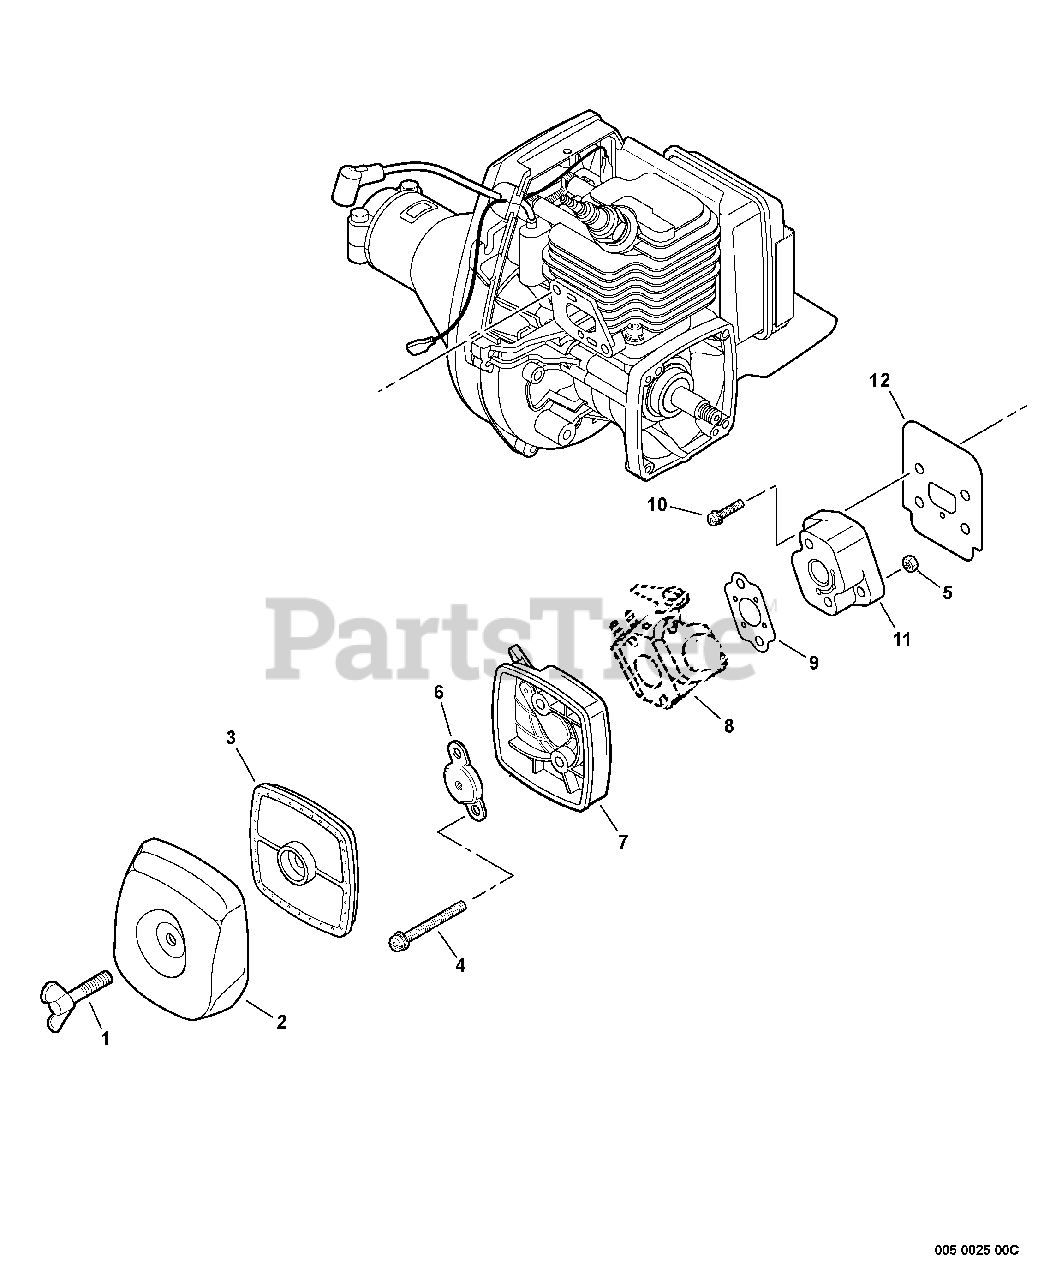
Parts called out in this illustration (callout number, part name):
1	BOLT, WING 5×20
2	COVER, AIR FILTER - GRAY
3	FILTER, AIR - SINGLE LAYER
4	SCREW 5×65
5	NUT M5
6	PLATE, PREVENT
7	CASE, AIR FILTER - GRAY
8	CARBURETOR
9	GASKET, INTAKE
10	SCREW 5×20
11	INSULATOR, INTAKE
12	HEAT SHIELD, INTAKE
